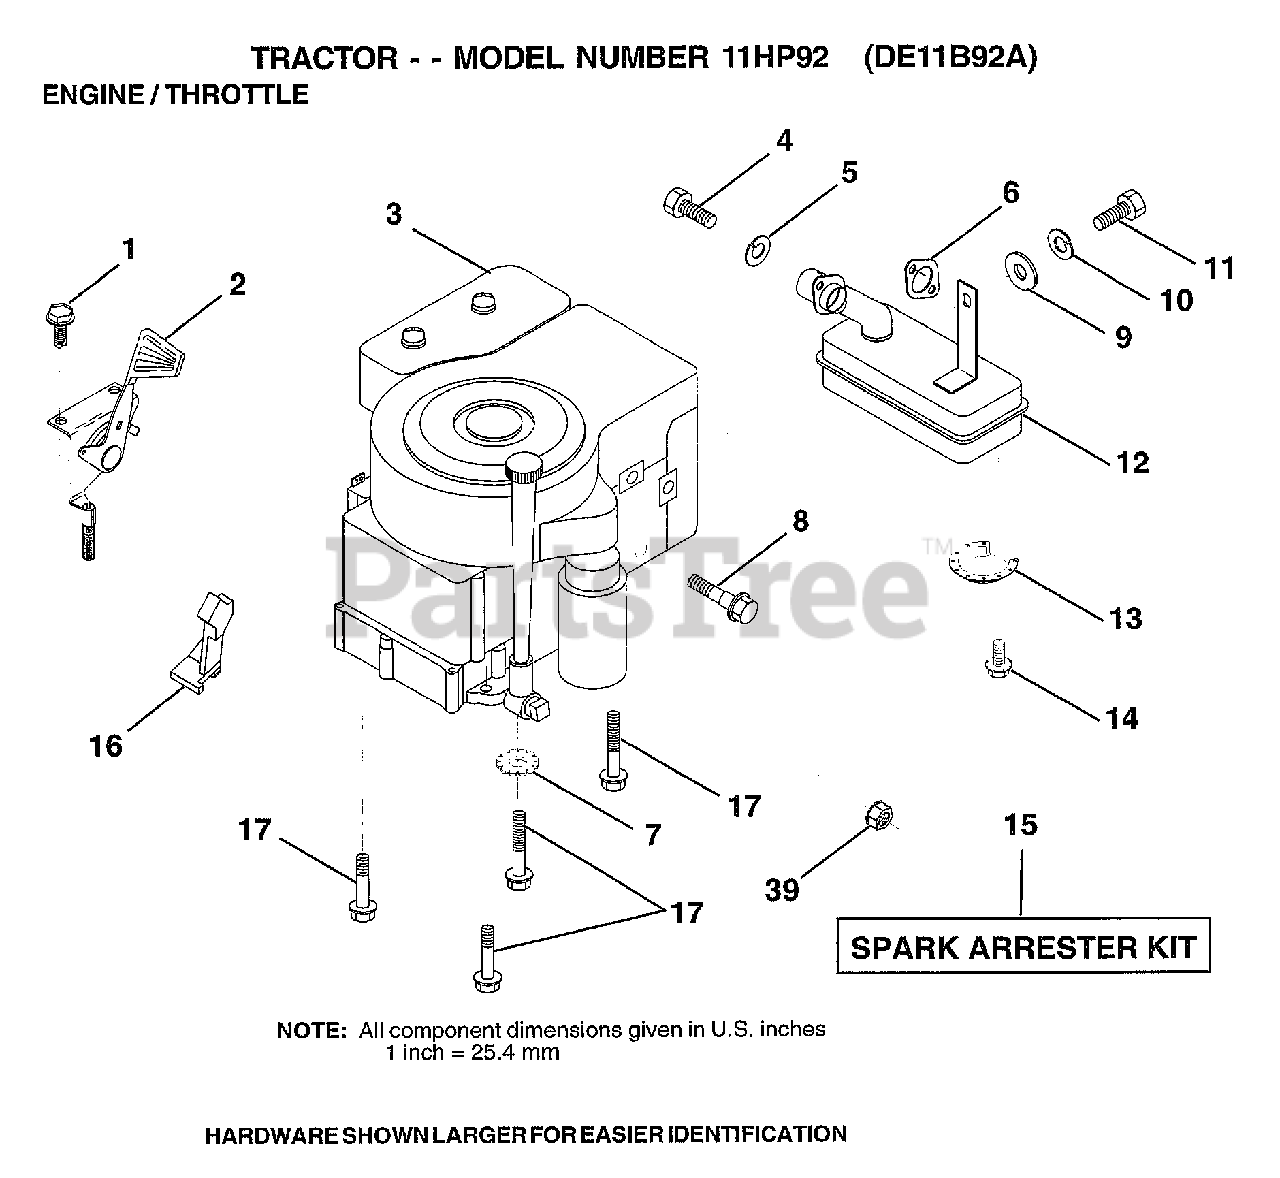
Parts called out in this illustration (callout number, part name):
1	SCREW LT
4	SCREW
5	LOCKWASHER
7	LOCKWASHER
8	BOLT T
10	LOCKWASHER
12	MUFFLER
13	DEFLECTOR.222573
16	"STOP,DASH THROTT"
17	SCREW LT
39	NUT
